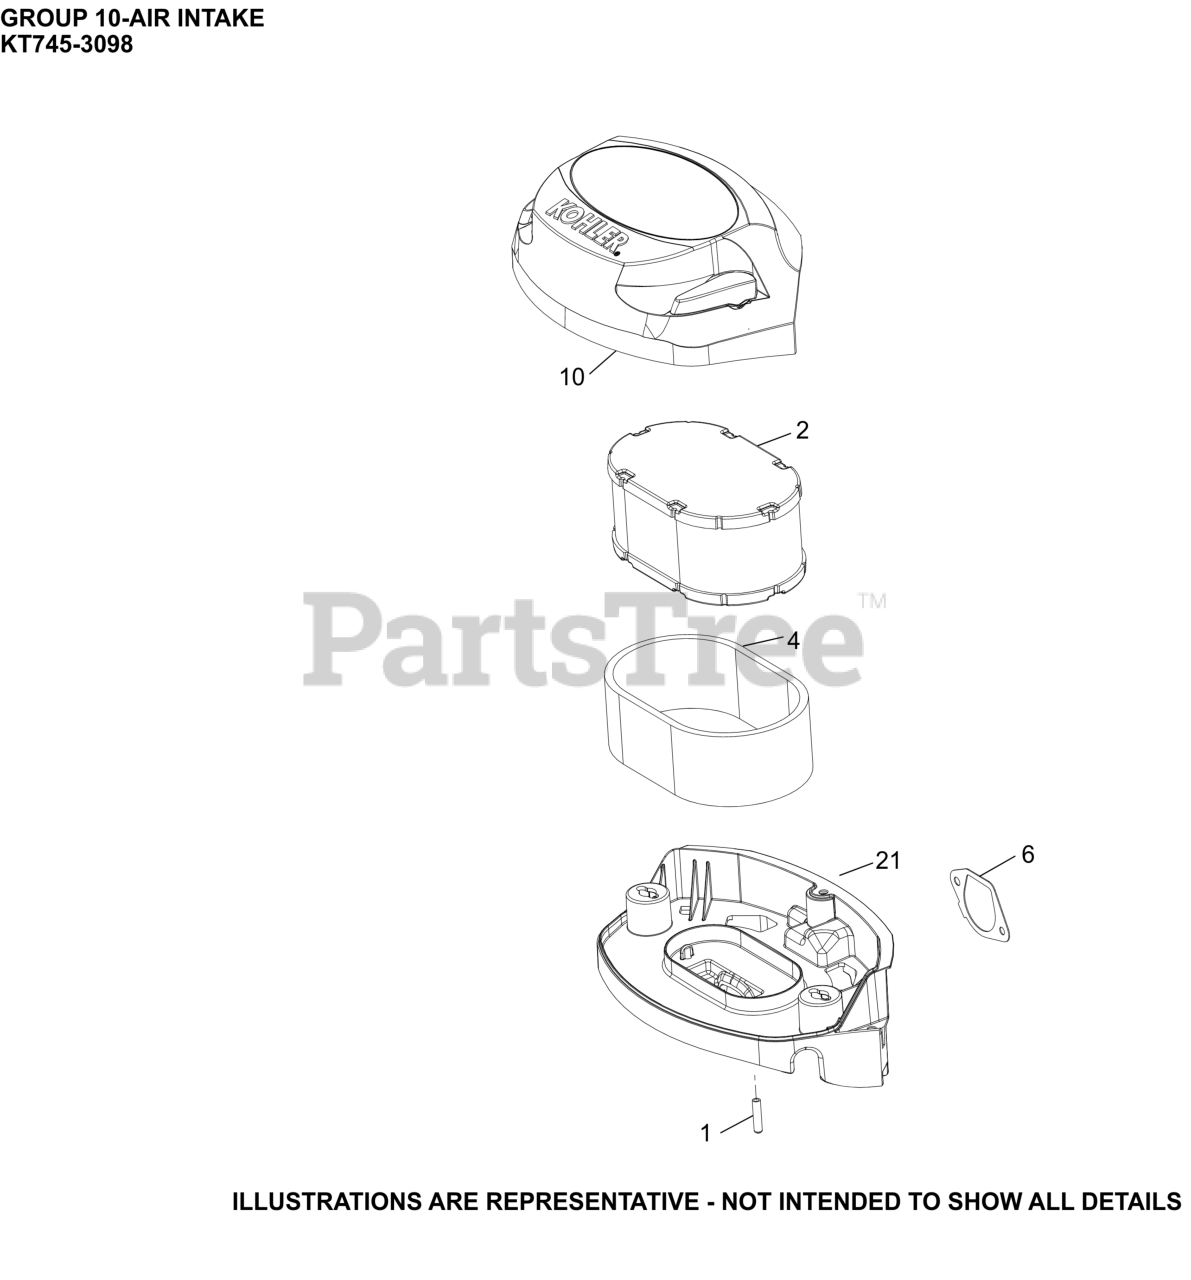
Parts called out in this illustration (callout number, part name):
1	CAP, MASKING
2	ELEMENT, AIR FILTER
4	ELEMENT, PRE-CLEANER
6	GASKET, AIR CLEANER BASE
10	COVER ASSY, AIR CLEANER
21	BASE ASSEMBLY, AIR CLEANER
